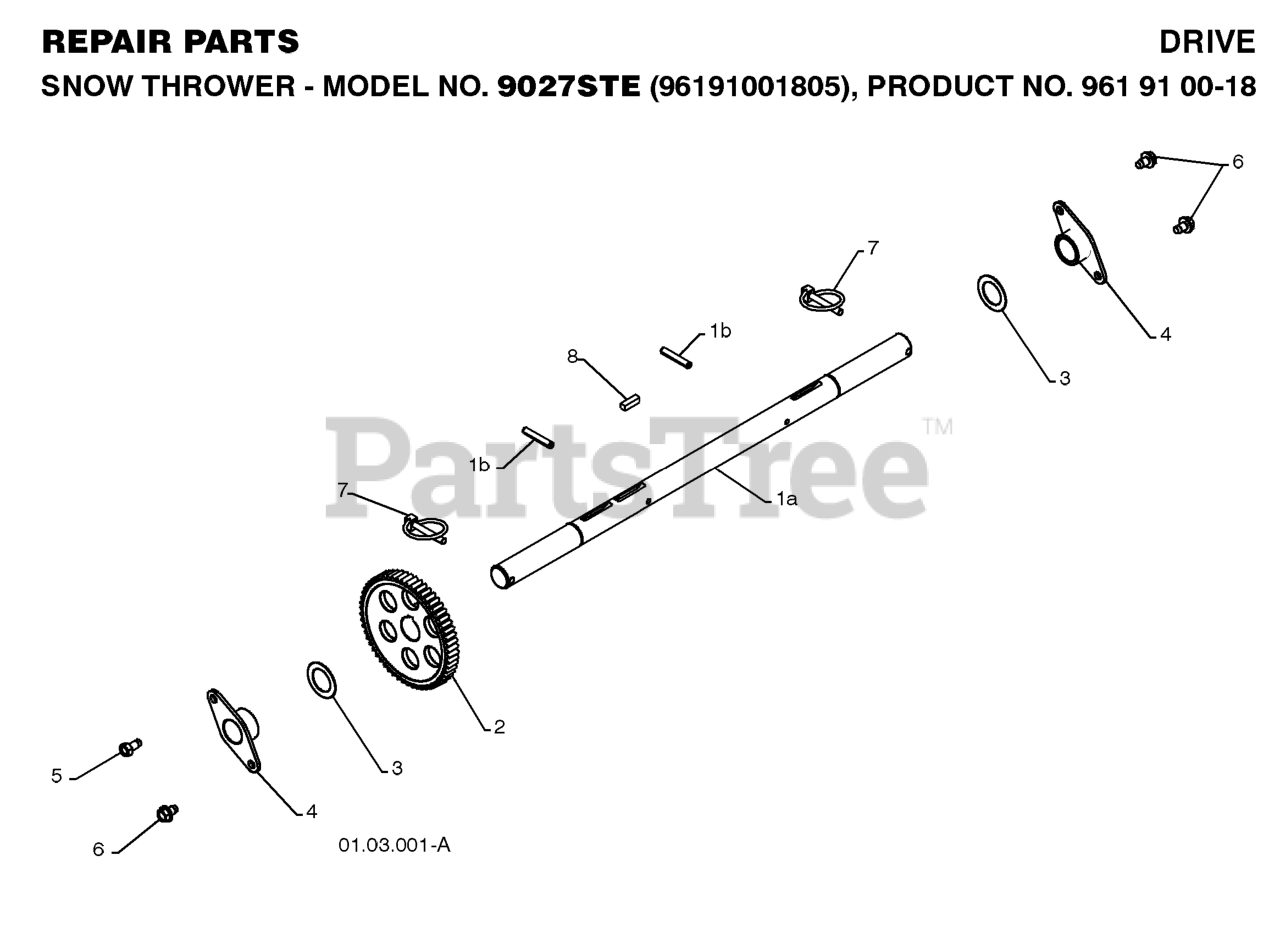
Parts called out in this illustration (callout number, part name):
1	AXLE.ASM.SHAFT.W/ROLLPIN.PS
1A	SHAFT.AXLE.POWER.STEERING
1B	PIN.ROLL.3/16
2	GEAR, AXLE (58T)
3	WASHER TRUST 1"
4	BEARING, AXLE
6	Screw 5/16-18 x 1/2 Hex, Self Tapping 5/16-18 x 1/2
7	PIN KLIK, 1/4
8	KEY, SQUARE 1/4 X .875
